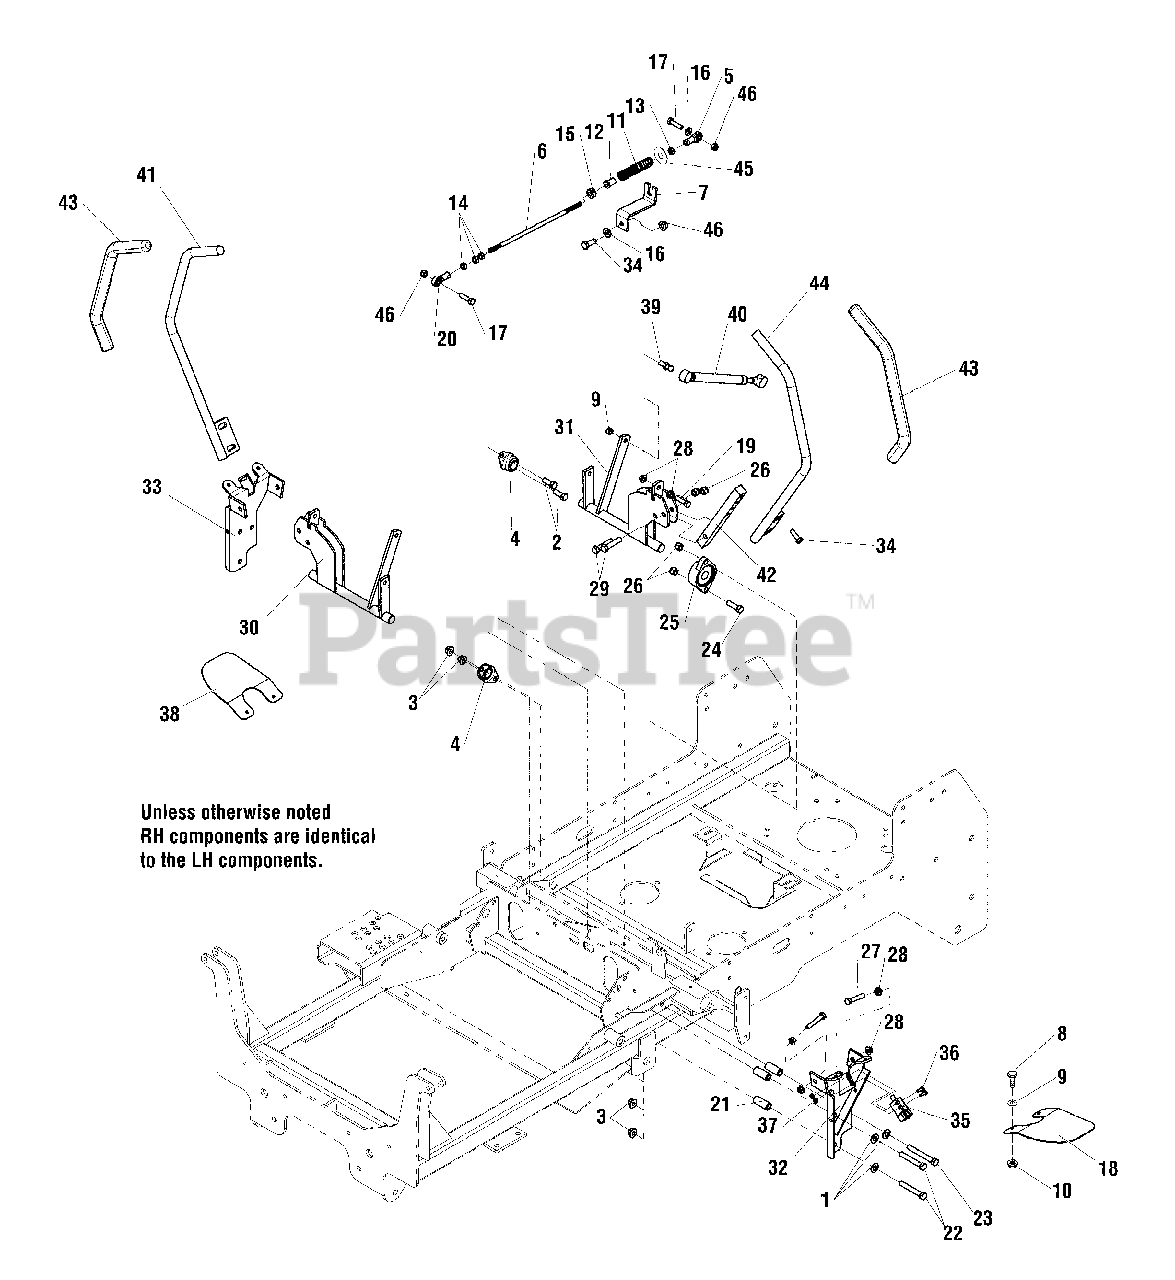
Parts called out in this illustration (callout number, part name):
1	WASHER, 3/8 SAE
2	BOLT, 3/8-16 X 1 GD5 YZ
3	NUT, 3/8-16 HEX NYLOCK FLANGE
4	BEARING, BRONZE FLANGE, 3/4
5	BALL JOINT 5/16-24 LH FEMALE STAMPED STL
6	ROD, HYDRO LINKAGE
7	MOUNT, REVERSE RETURN - BLK
8	BOLT, 1/4-20 X 3/4 GD5 YZ
9	WASHER, 1/4 SAE (5025154)
10	NUT, 1/4-20 HEX NYLOCK FLANGE (5025391)
11	SPRING, REVERSE RETURN
12	BUSHING, NYLON
13	NUT, 5/16-24 HEX, LH
14	NUT, 5/16-24 HEX
15	COLLAR, 5/16 SET
16	WASHER, 5/16" SAE
17	BOLT, 5/16-18 X 1-1/4 GD5 YZ
18	PLATE, HAND GUARD, LH - BLK
19	BOLT, 5/16-18 X 1-1/8 GD5
20	BALL JOINT 5/16-24 RH FEMALE STAMPED STL
21	SPACER, .39 X .63 X 1.50
22	BOLT, 3/8-16 X 2-1/2 GD5 YZ
23	BOLT, 3/8-16 X 3 GD5 YZ
24	BOLT, 3/8-16 X 1-1/4 GD5
25	BEARING, FLANGE
26	NUT, 3/8-16 HEX NYLON LOCK
27	BOLT, 5/16-18 X 1-3/4 GD5 TFL
28	NUT, 5/16-18 HEX SERRATED FLANGE (LARGE)
29	BOLT, 3/8-16 X 1-3/4 GD5
30	WELD, CONTROL SHAFT, RH - BLK
31	WELD, CONTROL SHAFT, LH - BLK
32	WELD, NEUTRAL LOCK, LH - BLK
33	WELD, NEUTRAL LOCK, RH - BLK
34	SCREW-HEX WSHR HD TAPTT5/16-18X0.750BLK
35	SWITCH, PLUNGER, N.O.
36	SCREW, #10-24 X 1/2 ROUND PHILLIPS
37	NUT, #10-24 HEX
38	PLATE, HAND GUARD, RH - BLK
39	10MM BALL STUD, 5/16-18 X 3/4 THDS
40	DAMPENER, CONTROL,#(P6709/P3610)
41	WELD, HANDLE MOTION CONTROL, RH - BLK
42	MOUNT, CONTROL ARM - BLK
43	GRIP, FOAM, 3/4 ID, 16 LONG
44	WELD, HANDLE MOTION CONTROL LH - BLK
45	WASHER, 3/8 X 1" X 1/16, NYLON F/W
46	NUT, 5/16-18 HEX NYLOCK FLANGE
